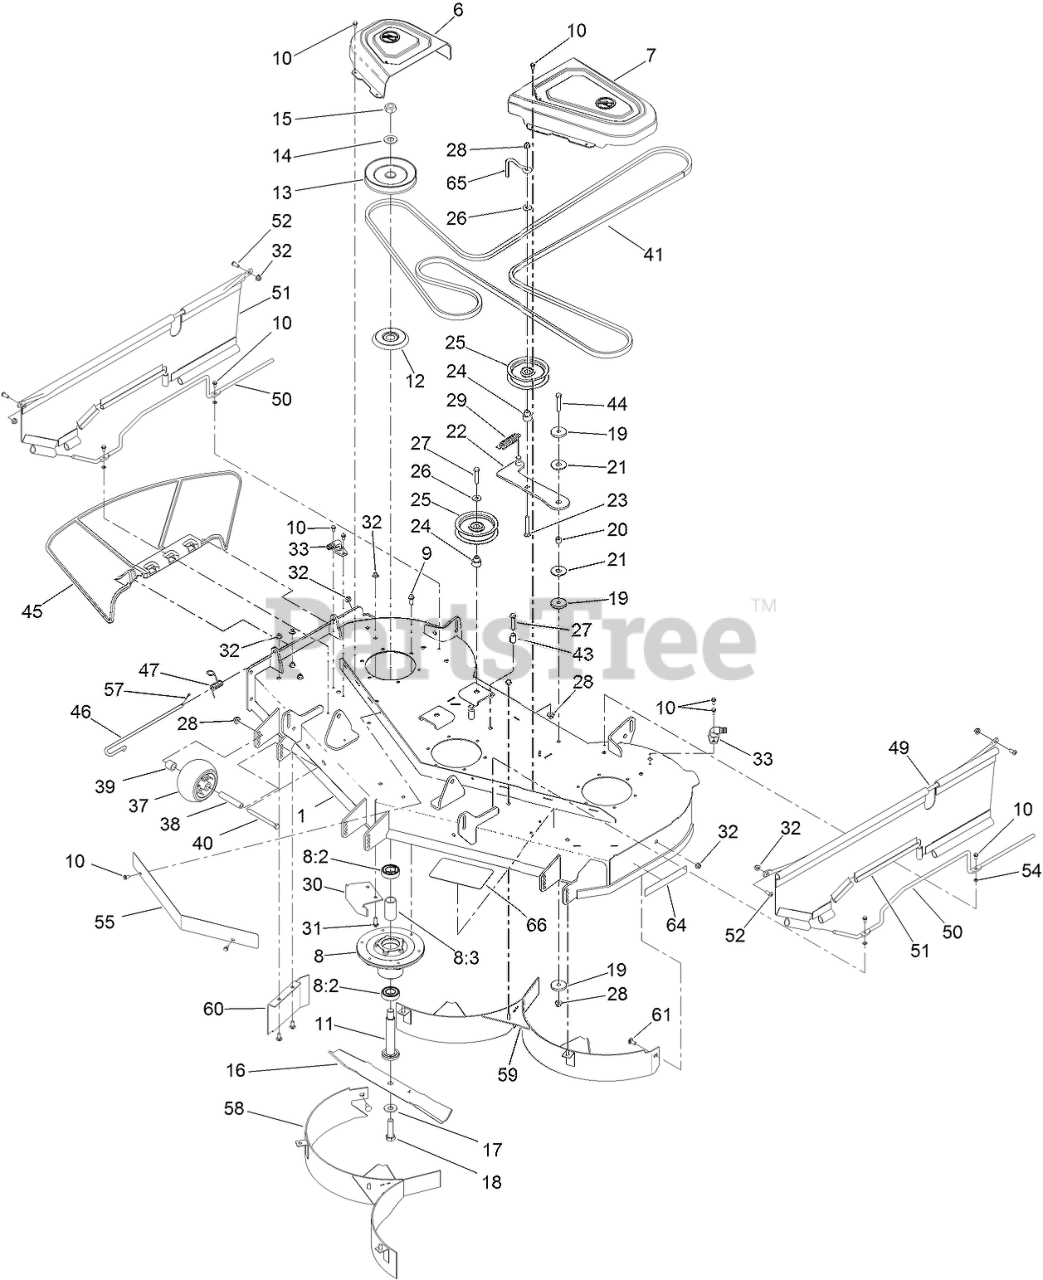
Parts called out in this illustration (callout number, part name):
1	DECK ASM
6	COVER-BELT, RH
7	COVER-BELT, LH
8	SPINDLE ASM
8:2	BEARING-BALL
8:3	SPACER-BEARING
9	SCREW-TAPTITE
10	SCREW-HWH
11	SHAFT-SPINDLE
12	SHIELD-BEARING
13	PULLEY
14	WASHER
15	NUT-HEX
16	BLADE-MULCH, 18.75 INCH
17	WASHER-BELLEVILLE
18	SCREW-BLADE
19	WASHER-PLAIN
20	BUSHING-LEVER, LIFT
21	WASHER-FRICTION, COMPOSITE
22	ARM-IDLER
23	SCREW-CARR
24	BUSHING-IDLER
25	PULLEY-IDLER, FLAT
26	WASHER-HARDENED
27	SCREW-HH
28	NUT-HF, NI
29	SPRING-EXTENSION
30	BAFFLE-CUTOFF
31	SCREW-CARR
32	NUT-HF, NI
33	FITTING-WASHOUT
37	ROLLER-SCALP, ANTI
38	TUBE-SPANNER
39	SPACER-AXLE, REAR
40	SCREW-HH
41	V-BELT
43	SPACER
44	SCREW-HH
45	DEFLECTOR-DISCHARGE
46	PIN-CHUTE
47	SPRING-TORSION
49	ROD SUPPORT, UPPER
50	ROD SUPPORT, LOWER
51	SIDE GUARD ASM
52	SCREW-HSBH
54	NUT-RETAINING
55	SHIELD-FRONT
57	PIN-COTTER
58	BAFFLE-RECYCLER
59	BAFFLE-RECYCLER, LH
60	GUARD-BAFFLE
61	BOLT-CARR
64	DECAL-RECYCLER
65	BELT GUIDE - IDLER
66	TREAD-STEP
